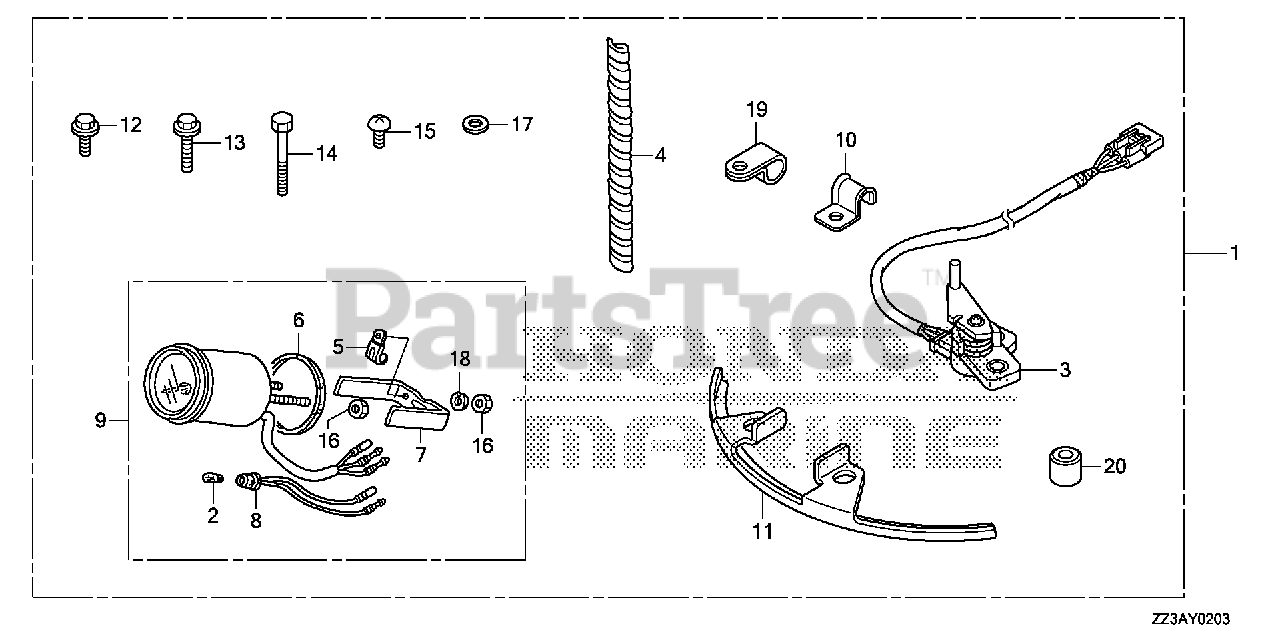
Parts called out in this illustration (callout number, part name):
1	METER KIT, RUDDER (WHITE)
1	METER KIT, RUDDER (BLACK)
2	BULB, WEDGE BASE (12V 1.7W)
3	SENSOR ASSY., RUDDER
4	TUBE, SPIRAL
5	CLAMP
6	GASKET
7	BRACKET
8	SOCKET
9	METER ASSY., RUDDER (BLACK)
10	CLAMP, TUBE
11	PLATE, STEERING ANGLE SENSOR
12	BOLT, FLANGE (6X12)
13	BOLT, FLANGE (6X20)
14	BOLT, HEX. (6X35)
15	SCREW, PAN (6X8)
16	NUT, HEX. (4MM)
17	WASHER, PLAIN (6MM)
18	WASHER, SPRING (4MM)
19	CLIP (14MM)
20	COLLAR, DISTANCE (6.5X16X14.5)
